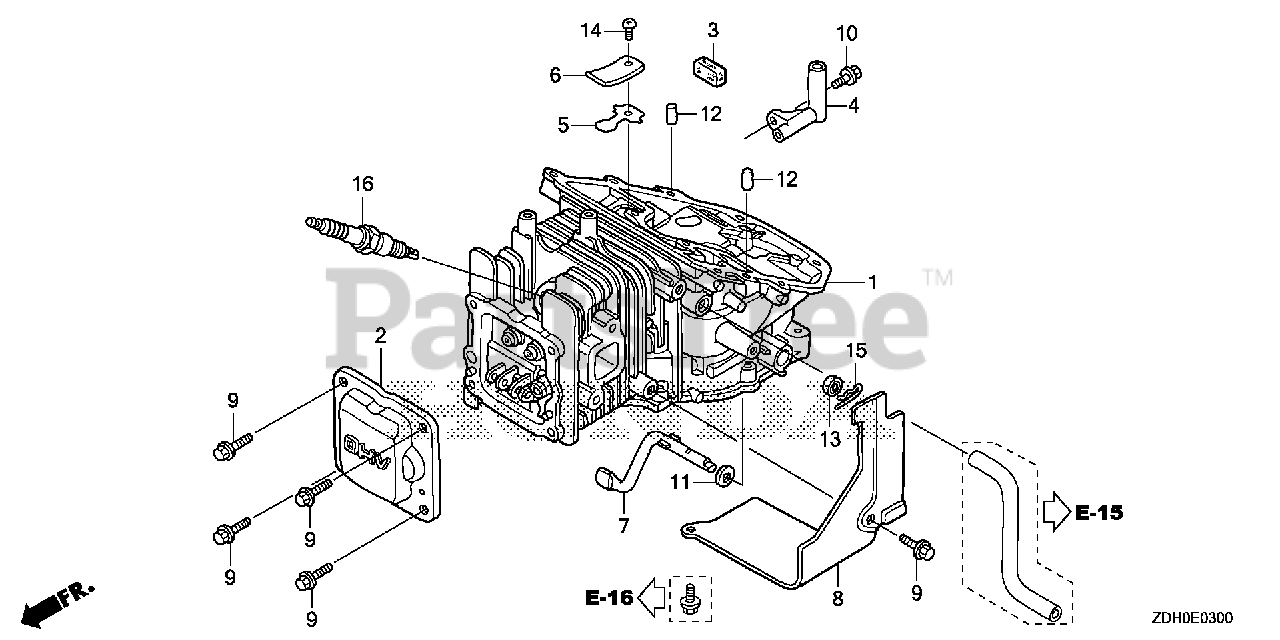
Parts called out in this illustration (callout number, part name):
2	COVER, HEAD
3	FILTER, BREATHER
4	PIPE, BREATHER
5	VALVE, OIL OUTLET
6	PLATE, STOPPER
7	SHAFT, GOVERNOR ARM
9	BOLT, FLANGE (5X12)
10	BOLT (4X10)
11	WASHER (5.2X9)
12	ROLLER (6X14.8)
13	OIL SEAL (5X11X5)
14	SCREW, PAN (3X5)
15	PIN, LOCK (6MM)
16	SPARK PLUG (U14FSR-UB) (DENSO)
16	SPARK PLUG (CR4HSB) (NGK)
16	SPARK PLUG (U16FSR-UB) (DENSO)
16	SPARK PLUG (CR5HSB)
